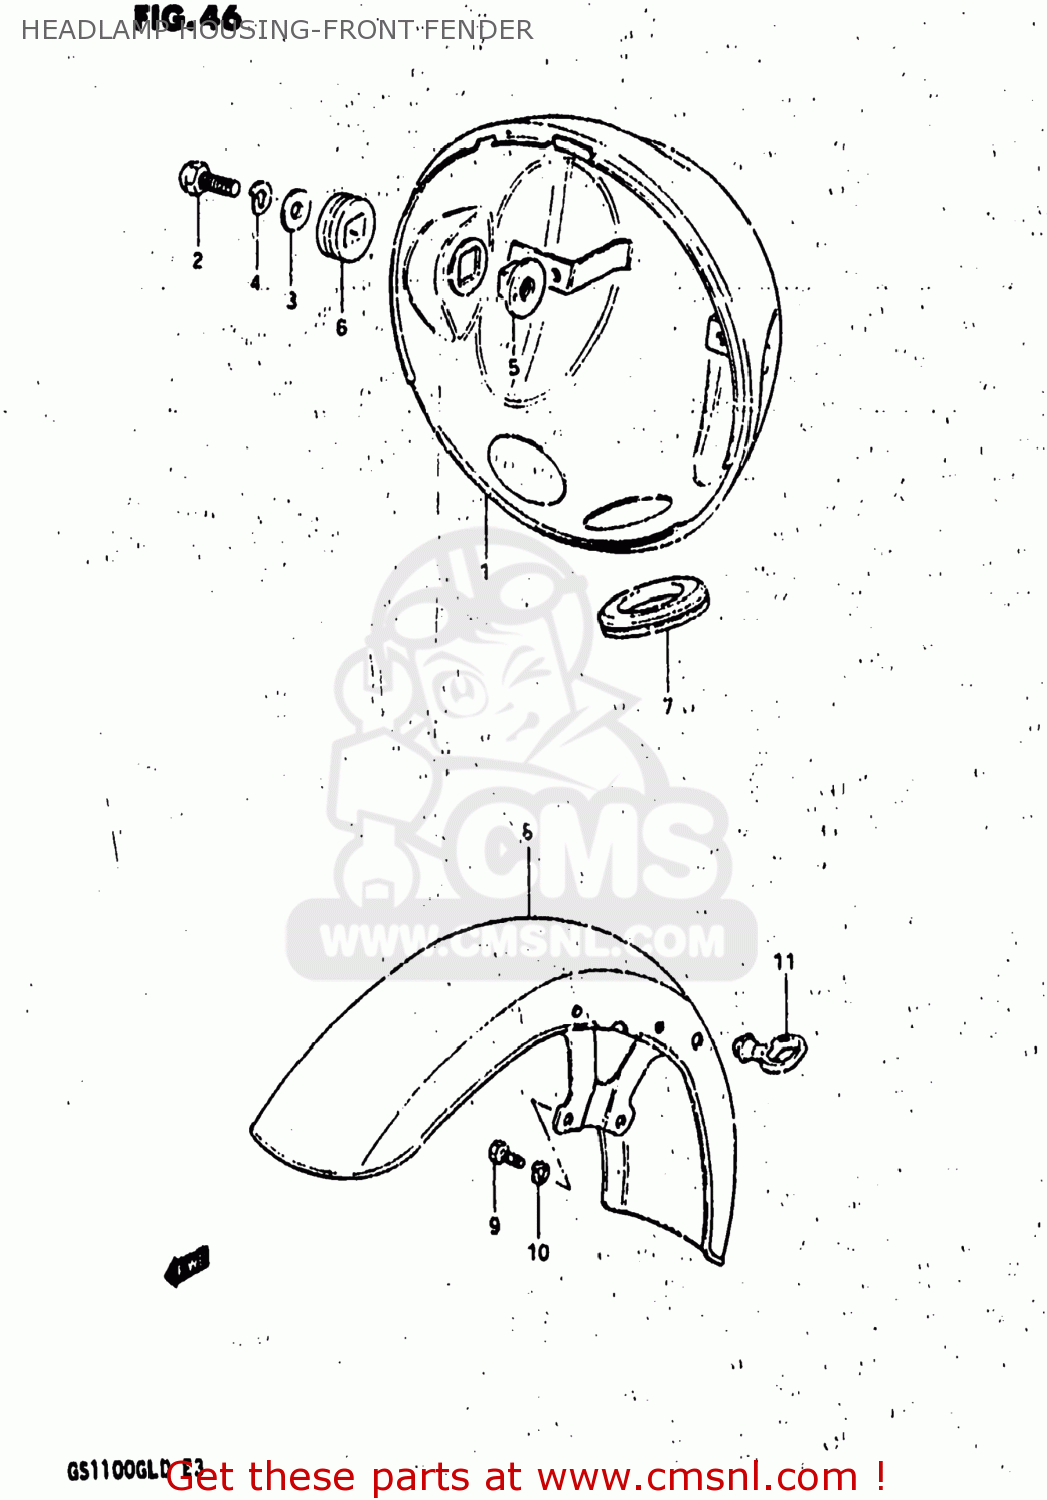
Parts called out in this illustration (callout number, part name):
1	HOUSING,HEADLAMP
2	BOLT
3	WASHER
4	LOCK WASHER
5	SPACER,HEADLAMP HOUSING
6	CUSHION,HEADLAMP HOUSING
7	GROMMET,HEADLAMP HOUSING
8	FENDER,FR
9	BOLT
10	LOCK WASHER
11	GUIDE,CABLE
